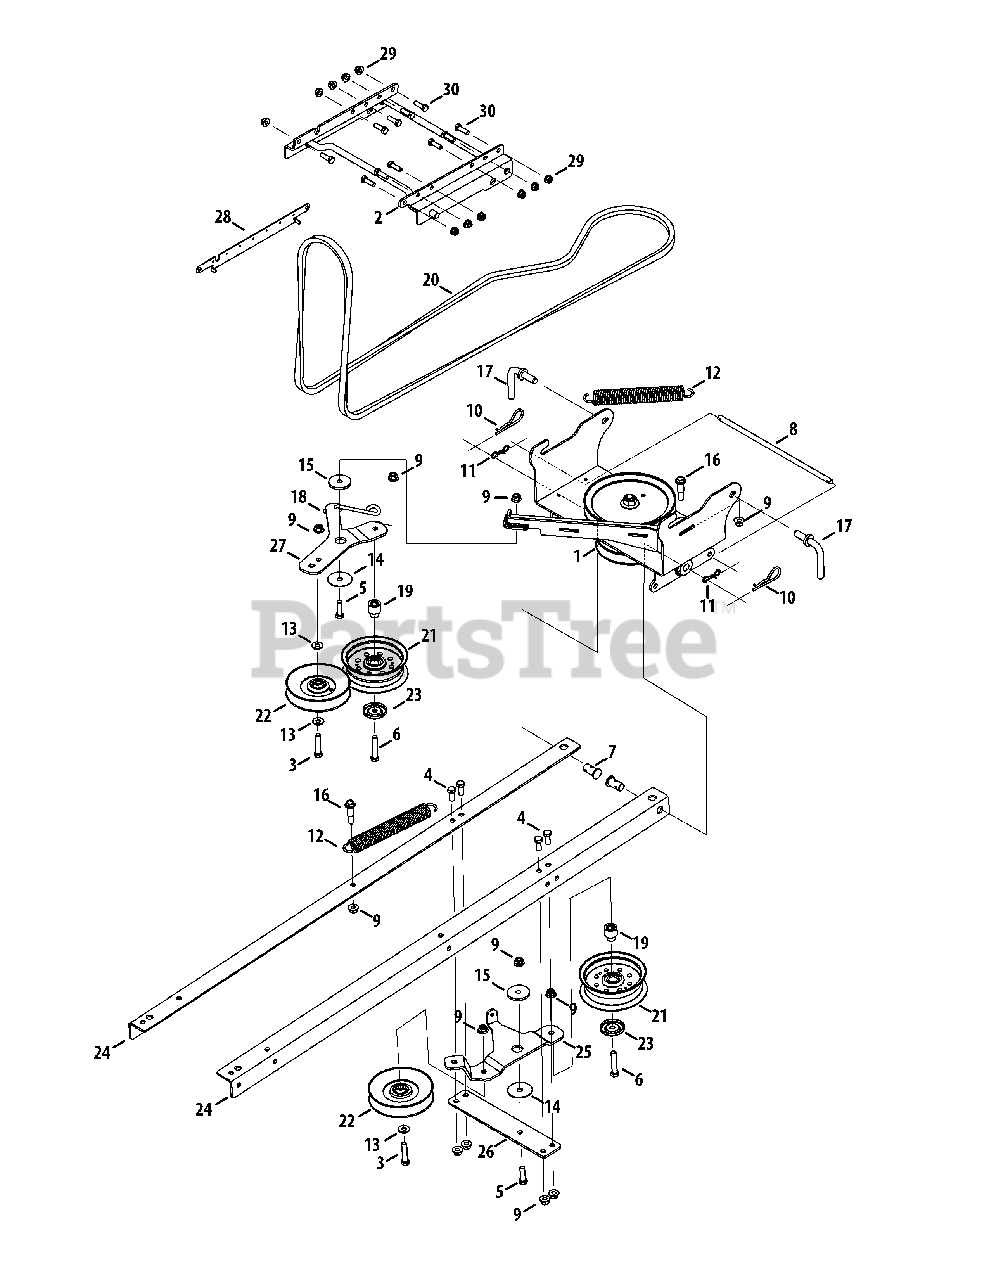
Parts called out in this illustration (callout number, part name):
1	Spindle Housing
1	Blade Spindle Shaft
1	V Pulley 7.25 Dia
1	V Pulley 5.57 Dia
3	Hex Screw, 3/8-16 x 1.75
4	Hex Screw, 3/8-16 x .880
5	Hex Screw, 3/8-16 x 1.25
6	Hex Screw, 3/8-16 x 2.00
7	Clevis Pin, .62
8	Shaft, .375 x 12.3450
9	Flange Lock Nut, 3/8-16
10	Cotter Pin, .148 x 3.00
11	Pin, 7/16-1/2
12	Extension Spring, 1.25 x 8.5
13	Flat Washer, .385 x .870 x .092
14	Thrust Washer, .445 x 1.92 x .060
15	Shoulder Spacer, .8840 x .190
16	Shoulder Bolt, 3/8-16 x .50 x .925
17	Lock Rod, .500
18	Sprin Rod Hook
19	Idler Pivot Shoulder Spacer
20	V-Belt, 114.3
21	Idler Pulley, 4.50
22	Idler Pulley, 5.06
23	Pulley Cap
25	Idler Pivot Bracket
27	Idler Pivot Bracket
28	Hanger Bracket Template
29	Hex Screw, 5/16-18 x 1.00
30	Flange Lock Nut, 5/16-18
